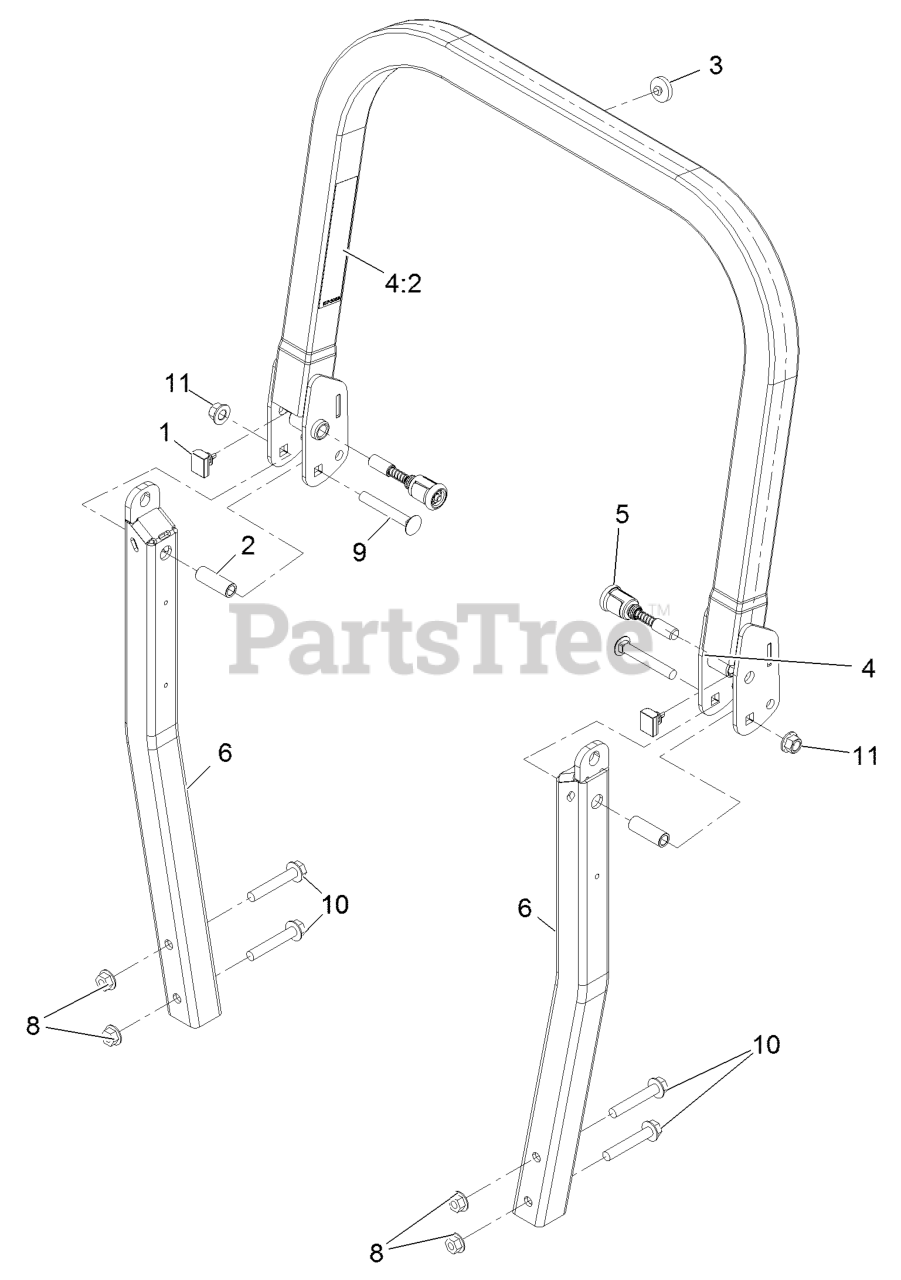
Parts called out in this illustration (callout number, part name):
1	BUMPER-ROPS
3	BUMPER-PUSH-IN, RUBBER
4	UPPER ROPS ASM
4:2	DECAL-WARNING
5	PIN-SPRING
6	ASM-Lwr ROPS Leg
8	NUT-HHF
9	SCREW-CARR
10	SCREW-HF
11	Nut-Lock 1/2-13
